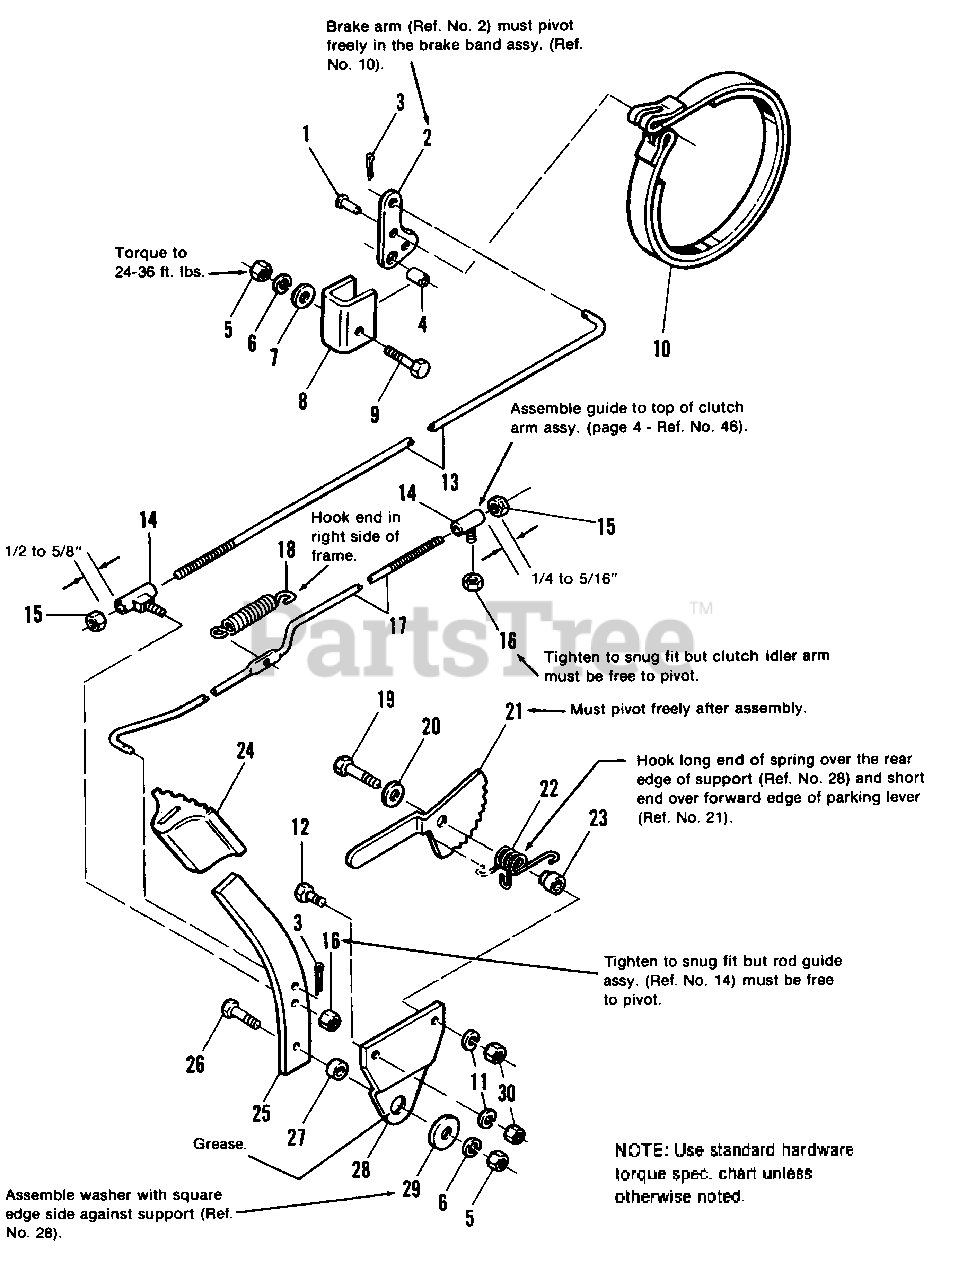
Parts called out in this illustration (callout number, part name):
2	ARM, Brake
3	PIN, Cotter, 3/32 x 3/4
5	NUT, Hex, 3/8-16
6	LOCKWASHER, 3/8
7	WASHER, Plain, 5/16
8	BRACKET, Brake
9	BOLT, Special
10	BRAKE BAND ASSY.
11	LOCKWASHER, 5/16
12	CAPSCREW, Hex, 5/16-18 x 3/4
13	ROD, Brake
14	ROD GUIDE ASSY.
15	LOCKNUT, Esna, 5/16-18
16	LOCKNUT, Hex, 5/16-18
17	ROD, Clutch
19	CAPSCREW, Hex, 5/16-18 x 1-1/2
20	WASHER, Plain, 11/32
21	LEVER, Parking Brake
22	SPRING, Torsion
24	PAD, Pedal
25	PEDAL, Brake
26	CAPSCREW, Hex, 3/8-16 x 1-1/4
28	SUPPORT, Brake Pedal
30	NUT, 5/16-18
